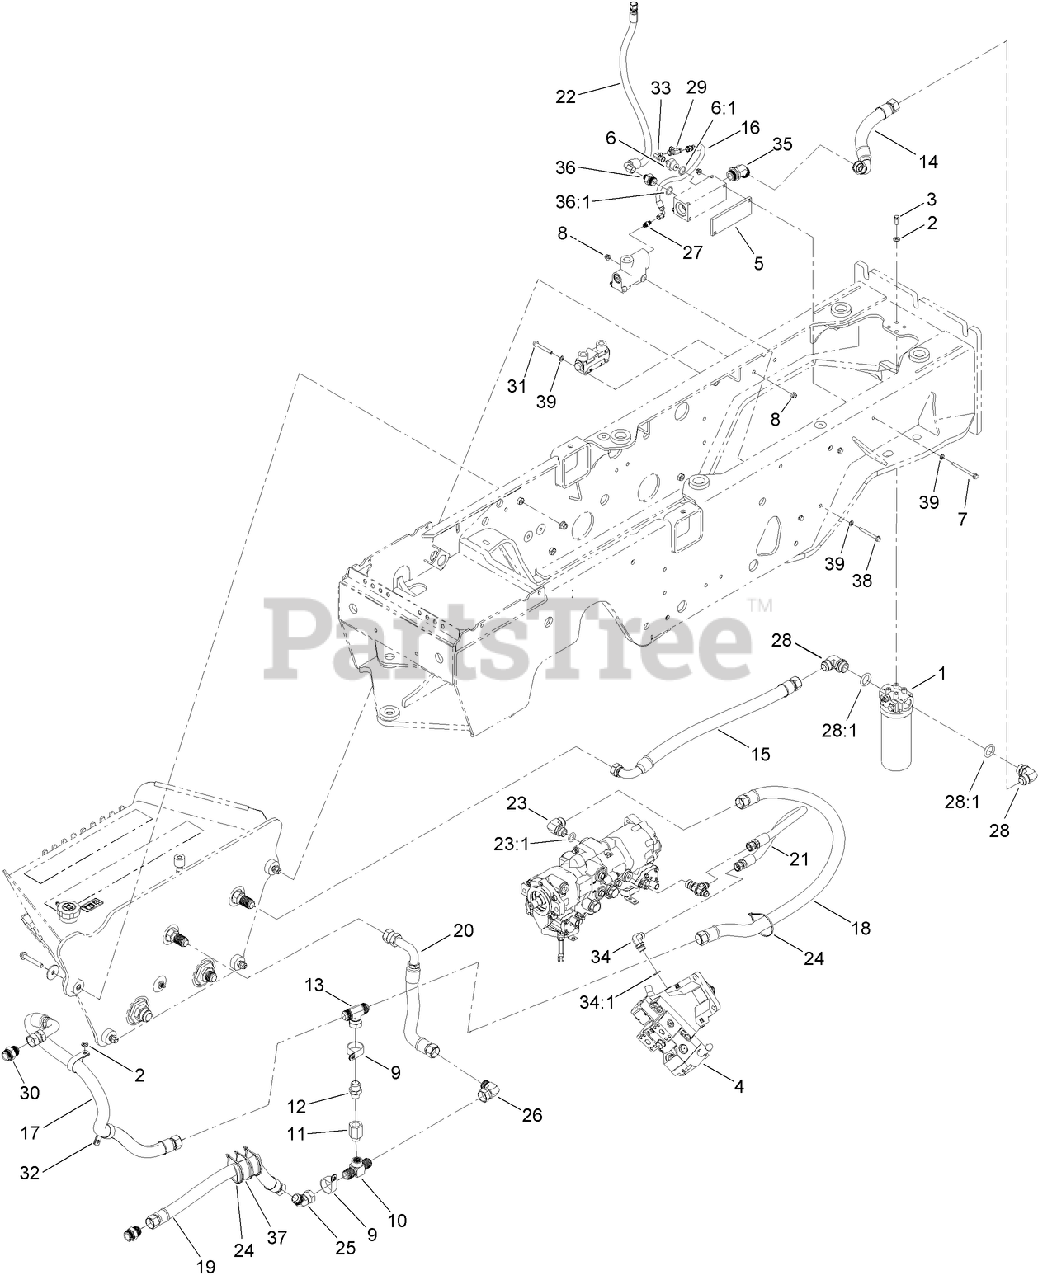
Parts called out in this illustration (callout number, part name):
1	OIL FILTER ASM
2	WASHER-FLAT
3	SCREW-HH
4	MOTOR ASM
5	SPACER
6	ADAPTER-STRAIGHT
6:1	O-RING
7	SCREW-HHF
8	NUT-LOCK, HHF
9	CLAMP-R
10	FITTING-TEE
11	VALVE-CHECK
12	ADAPTER
13	FITTING-TEE
14	HOSE ASM
15	HOSE ASM
16	HOSE ASM
17	HOSE ASM
18	HOSE ASM
19	HOSE ASM
20	HOSE ASM
21	HOSE ASM
22	HOSE ASM
23	FITTING-ELBOW, 90
23:1	O-RING
24	TIE-CABLE
25	FITTING-ELBOW, 45
26	FITTING-ELBOW, 90
27	FITTING-STRAIGHT
28	ELBOW-90 DEG
28:1	O-RING
29	FITTING-HYD, TEE
30	FITTING-STRAIGHT
31	SCREW-FLANGE
32	CLAMP-R
33	ELBOW-SWIVEL, 90 DEG
34	FITTING-ELBOW, 90 DEG
34:1	O-RING
35	FITTING-ELBOW, 45
36	FITTING-STRAIGHT
36:1	O-RING
37	PROTECTOR-HOSE
38	SCREW-HHF
39	WASHER-PLAIN
